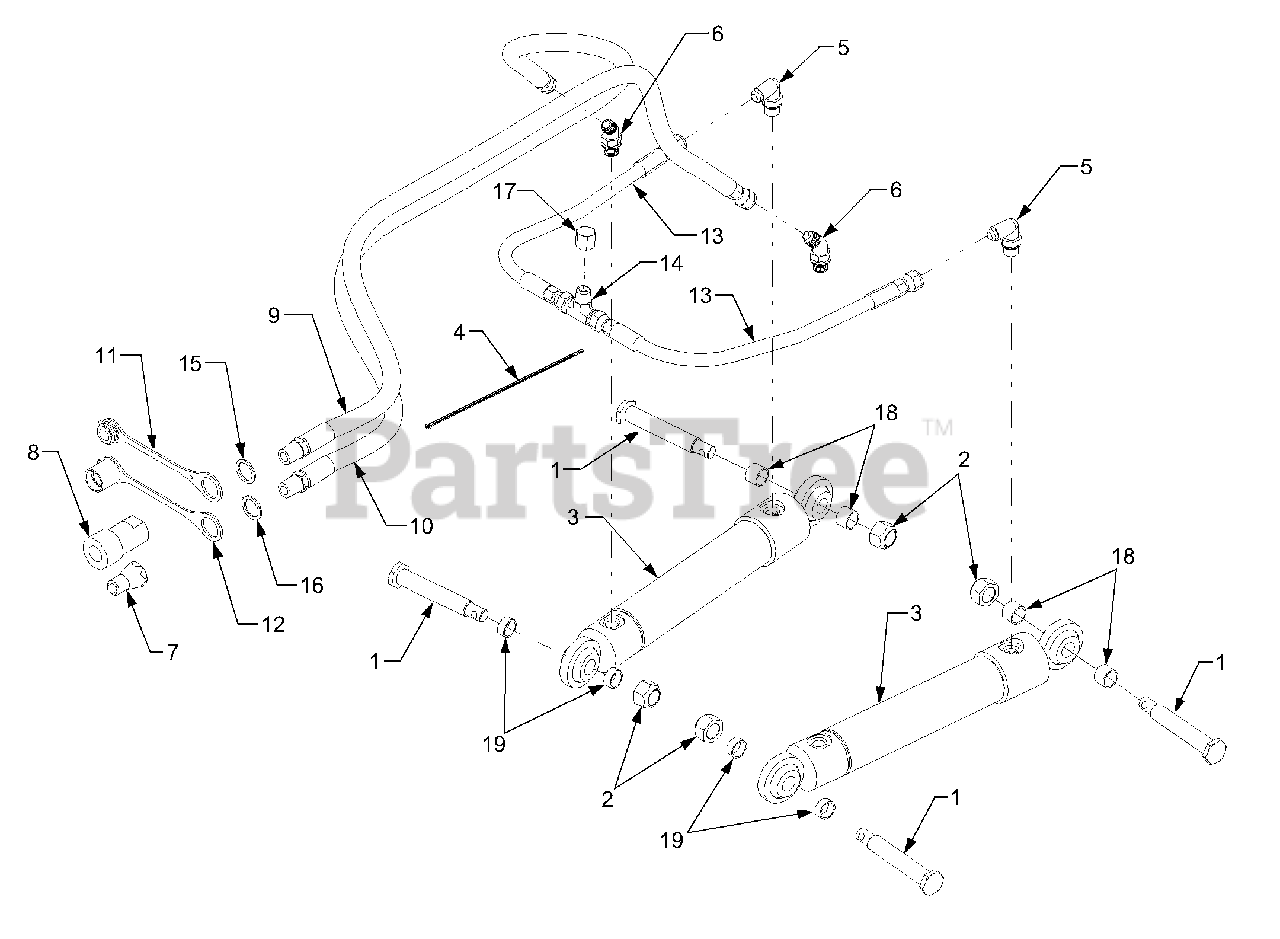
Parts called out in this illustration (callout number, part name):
1	Pin, Cylinder Mounting
2	Nut, Hex Lock, 5/8-18
3	Cylinder, Front Hitch Angle
4	Tie, Cable
5	Fitting, 90°.
6	Fitting, 45°.
7	Coupling, Hydraulic - Male
8	Coupling, Hydraulic - Female
9	Hose, Hydraulic, 1/4 ID x 42
10	Hose, Hydraulic, 1/4 ID x 46
11	Plug, Hydraulic Coupler - Male
12	Plug, Hydraulic Coupler - Female
13	Hose, Hydraulic, 1/4 ID
14	Fitting, Tee
15	Washer, Indicator - Red
16	Washer, Indicator - Yellow
17	Cap, Fitting
18	Spacer, Angle Cylinder - Long
19	Spacer, Angle Cylinder - Short
